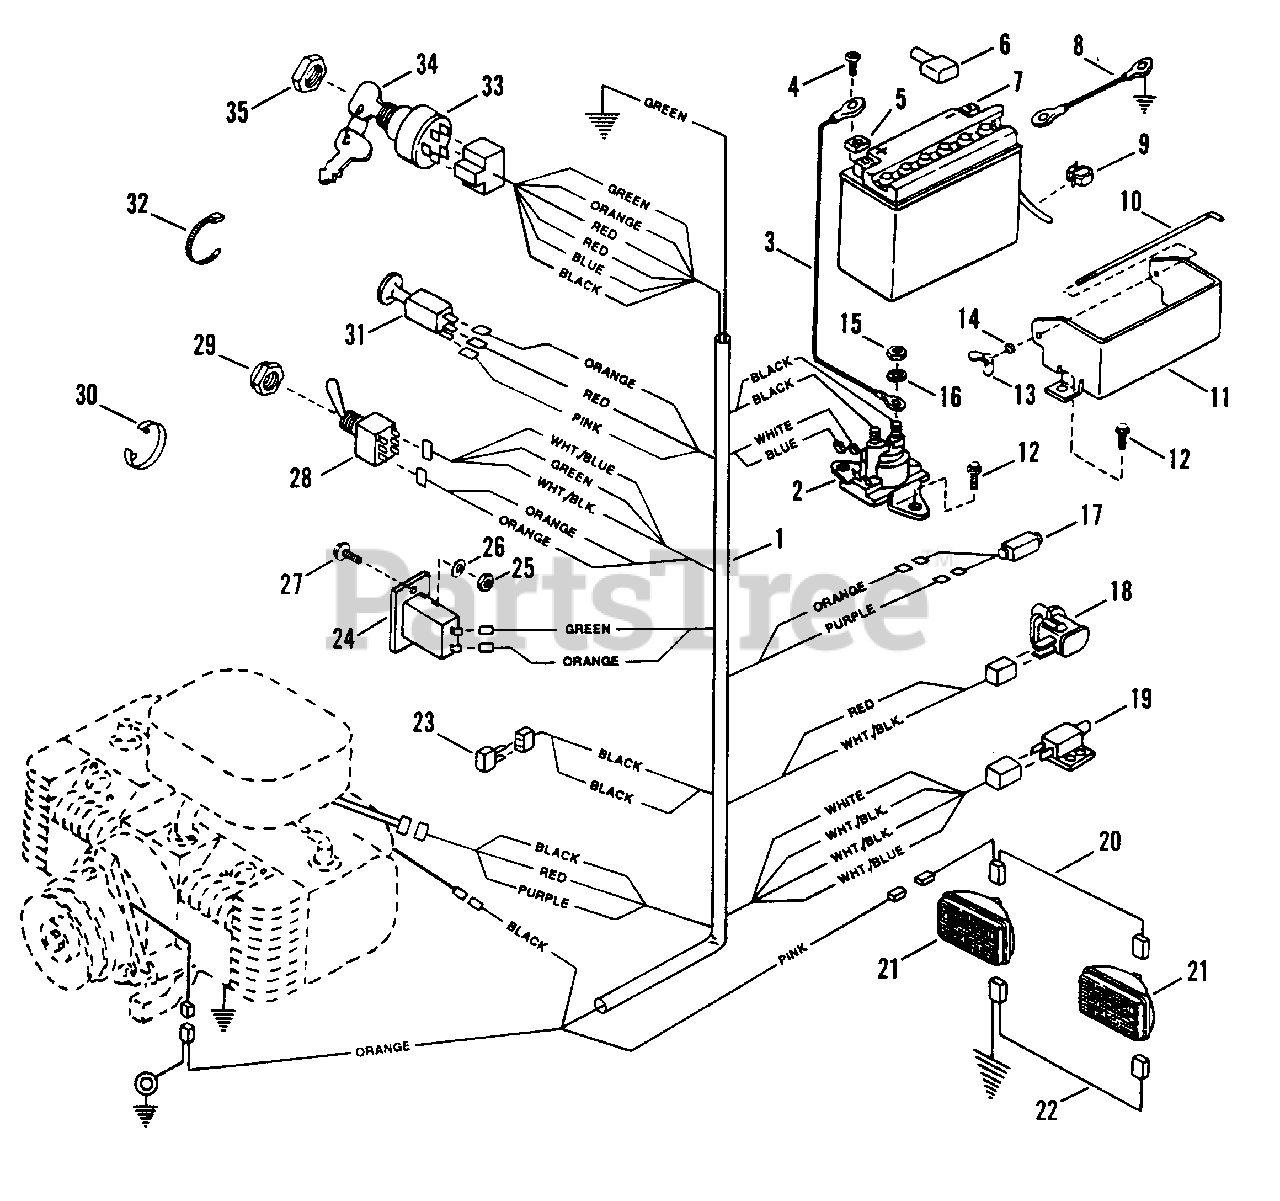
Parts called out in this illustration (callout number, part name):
1	HARNESS, Wiring
2	SOLENOID
3	WIRE, Battery / Solenoid (Black 16.5" 8 GA)
4	SCREW, M5 x 10 P.H. Torx
5	NUT, M5 x .08, Battery Terminal
6	COVER, Positive Terminal
7	BATTERY, 12 Volt, 20 Amp Hour
8	CABLE, Negative (Black)
9	CLIP, Battery Hose
10	CLAMP, Battery
11	BRACKET, Battery
12	SCREW, 1/4-20 x 5/8" Self-Tapping
13	WING-NUT, 1/4-20
14	WASHER, 1/4 Flat
15	NUT, 1/4-20 Special, Hex
16	WASHER, 1/4 Internal Tooth Lock
17	OIL LIGHT
18	SWITCH, Seat Interlock, Gray (NC)
19	SWITCH, Clutch Interlock
20	HARNESS, Headlamp
21	HEAD-LAMP
22	HARNESS, Ground
23	FUSE, 20 Amp
24	HOURMETER
25	NUT, #6-32 Hex
26	WASHER, #6-32 Int. Tooth Lock
27	SCREW, #6-32 x 3/4" Machine
28	SWITCH, PTO
29	NUT, 1/4-20 Special, Hex
30	TIE, Cable
31	SWITCH, Headlamp
32	TIE, Wire
33	KEYSWITCH
34	KEY,
35	NUT, 5/8-32 Hex
